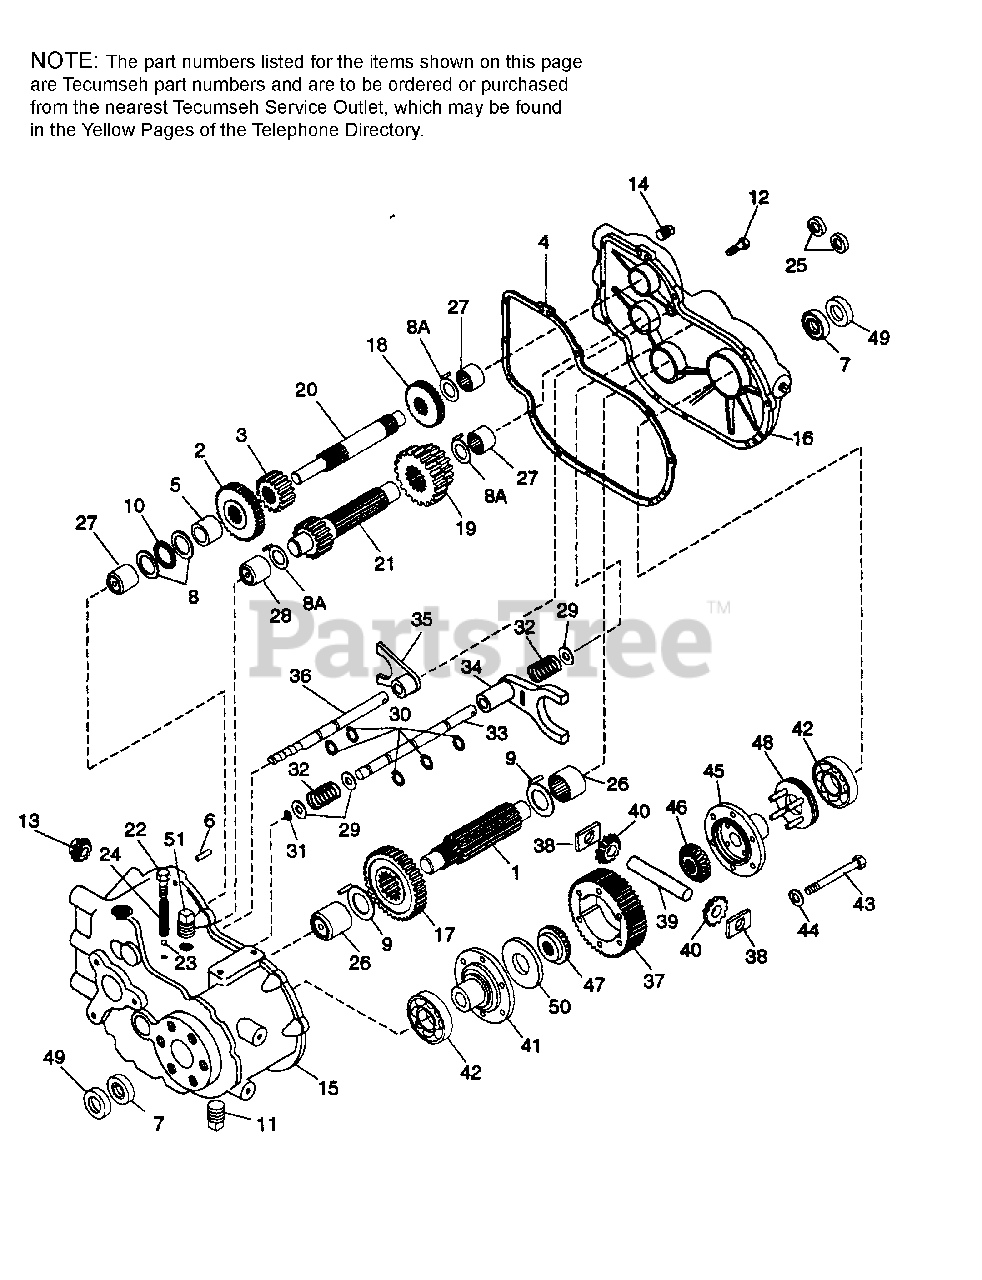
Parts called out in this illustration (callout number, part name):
1	PINION, OUTPUT
2	GEAR, BEVEL
3	GEAR, SPUR
4	GASKET, CASE & COVER
5	SPACER
6	PIN, DOWEL
7	SEAL, OIL
8	WASHER, THRUST
8A	WSHR, THRUST
9	WSHR, THRUST
10	BEARING, THRUST
11	PLUB, MAGNETIC DRAIN, 3/8-18
12	SCREW, HEX HD. THREADFORMING, 5/16-18 X 1
13	PINION, BEVEL
14	PLUB, PIPE, 1/8-27
15	CASE ASSY., TRANSAXLE
16	COVER, ASSY., TRANSAXLE
17	GEAR, OUTPUT
18	GEAR, SPUR
19	GEAR, CLUSTER
20	SHAFT, COUNTER
21	SHAFT & GEAR, SHIFTER
22	SCREW, HEX FLANGED HD., 1/4-20 X 5/8
23	BALL, STEEL, 3/16"
24	SPRING, SHIFTER FORK
25	SEAL, OIL
26	BEARING, NEEDLE
27	BEARING, NEEDLE
28	BEARING, NEEDLE
29	WASHER, THRUST
30	RING, RETAINING
31	RING, RETAINING
32	SPRING, COMPRESSION
33	ROD, SHIFT
34	FORK, SHIFT
35	FORK, SHIFT
36	ROD, SHIFT
37	GEAR, RING
38	BLOCK, DRIVE
39	PIN, DRIVE
40	PINION, BEVEL
41	CARRIER, DIFFERENTIAL
42	BEARING, BALL
43	SCREW, HEX FLANGED HD., 3/8-16 X 2-3/4
44	LOCKWASHER, 3/8"
45	CARRIER, DIFFERENTIAL
46	GEAR, BEVEL
47	GEAR, BEVEL
48	COLLAR ASSEMBLY, SHIFT
49	SPACER
50	WASHER, THRUST
51	PLUG, 3/8-18 SQ. HD. PIPE
